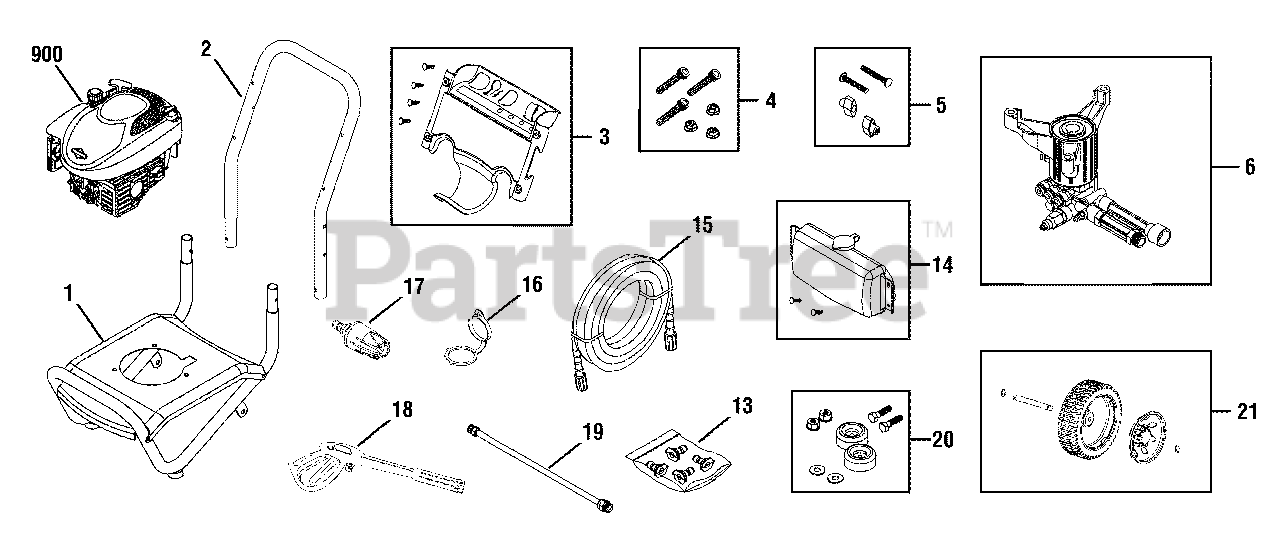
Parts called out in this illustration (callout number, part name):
1	BASE, w/ Mounts
2	HANDLE
3	KIT, Billboard Assy, w/Decals & Clips
4	KIT, Hardware, Pump Mounting
5	KIT, Hardware, Handle
6	PUMP
13	KIT, Spray Tips
14	ASSY, Chemical Tank
16	CAP, Chemical Container
17	ASSY, Turbo Max
18	GUN
19	EXTENSION
20	KIT, Vibration Mount
900	* ENGINE
